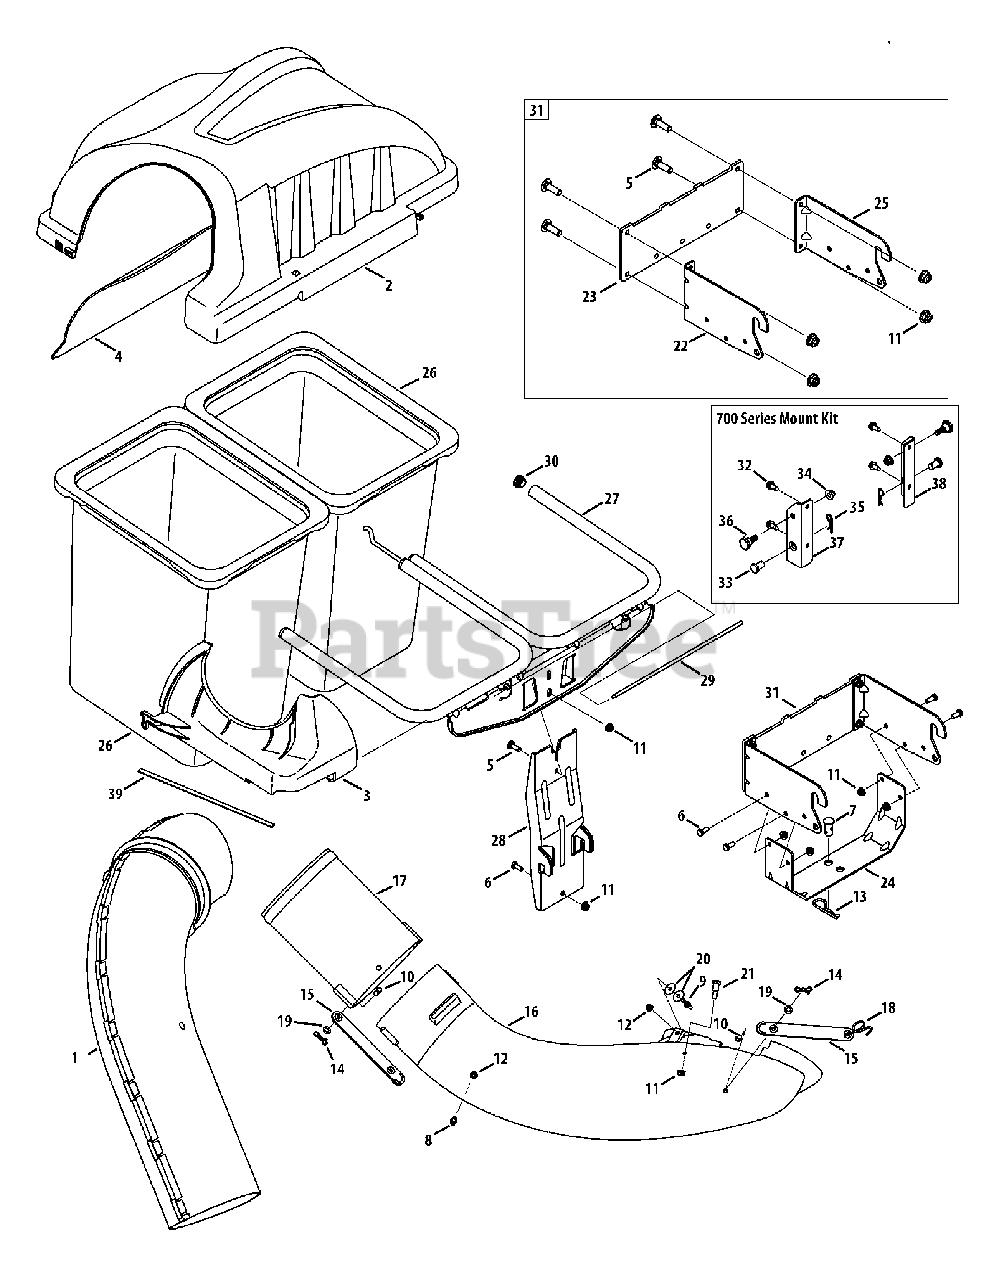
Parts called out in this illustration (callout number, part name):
1	Upper Chute Assembly
2	Double Bagger Cover Assembly
3	Upper Chute Support
4	Bagger Cover Screen
5	Carriage Screw, 5/16-18 x 1.00"
6	Hex Head Screw, 5/16-18 x .75"
7	Clevis Pin, .62" Dia.
8	Grass-catcher Pin, 1/4-20
9	Attachment Pin, 1/4 x 0.66 Lg.
10	Clevis Pin, 5/16 x .75 Lg.
11	Flange Lock Nut, 5/16-18
12	Flange Lock Nut, 1/4-20
13	Internal Cotter Pin, .148 x 3.00
14	Bow-Tie Cotter Pin, 72
15	Chute Strap, 6.00 Lg.
16	Bagger Discharge Chute, Elbow
17	Bagger Chute Adapter, 7 In.
18	Torsion Spring Hook
19	Flat Washer, .344 x .62 x .033
20	Flat Washer, .265 x .938 x .120
21	Shoulder Screw, .437 x .54
22	Mounting Bracket, RH
23	Universal Mounting Bracket
24	Universal Bracket Support
25	Mounting Bracket, LH
26	Grass-bag Assembly
27	Double Bag Support Assembly
28	Vertical Support Bracket
29	Cover Hinge Pin
31	Mounting Bracket Kit (Incl. ref. 22, 23, 25)
32	Tap Screw, 5/16-18 x .750
33	SCREW 3/8-16 x .75
34	Flange Lock Nut, 3/8-16
35	Click Pin, .092 x 1.64 Lg.
36	Shoulder Screw, .625 x .412
37	Mounting Bracket, RH
38	Mounting Bracket, LH
39	Self-Adhesive Foam Strip
